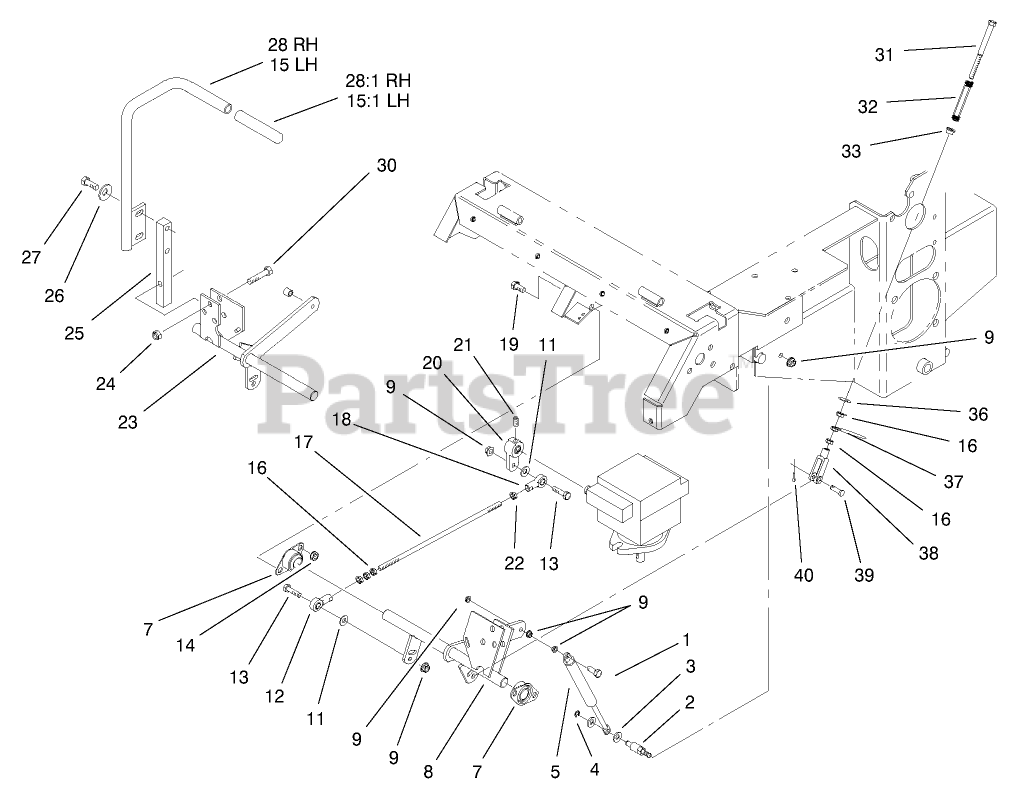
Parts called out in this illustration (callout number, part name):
1	SCREW-HH
2	PIN-DAMPER
3	WASHER-PLAIN
4	RING-RETAINING, EXT
5	DAMPER-CONTROL
7	BEARING-FLANGE, SIDE
8	LH Motion Control ASM
9	NUT-HF
11	WASHER-FLAT
12	BALLJOINT-RH
13	SCREW-HH
14	NUT-HHF, WHIZ
15	LH LEVER ASM
15:1	GRIP-CONTROL, MOTION
16	NUT-HEX
17	LINKAGE-PUMP/LEVER
18	BALLJOINT-LH
19	SCREW-HH
20	ARM-CONTROL, PUMP
21	SCREW-SET
23	RH Motion Control ASM
24	NUT-LOCK, NI
25	ARM-SHAFT, CONTROL
26	WASHER-BELLEVILLE
27	SCREW-HH
28	RH LEVER ASM
28:1	GRIP-CONTROL, MOTION
30	SCREW-HH
31	BOLT-RETURN, NEUTRAL
32	SPRING-RETURN, NEUTRAL
33	BUSHING-FLANGED
36	WASHER-FLAT
37	NUT-JAM
38	YOKE-ADJUSTABLE
39	PIN-CLEVIS
40	PIN-COTTER
